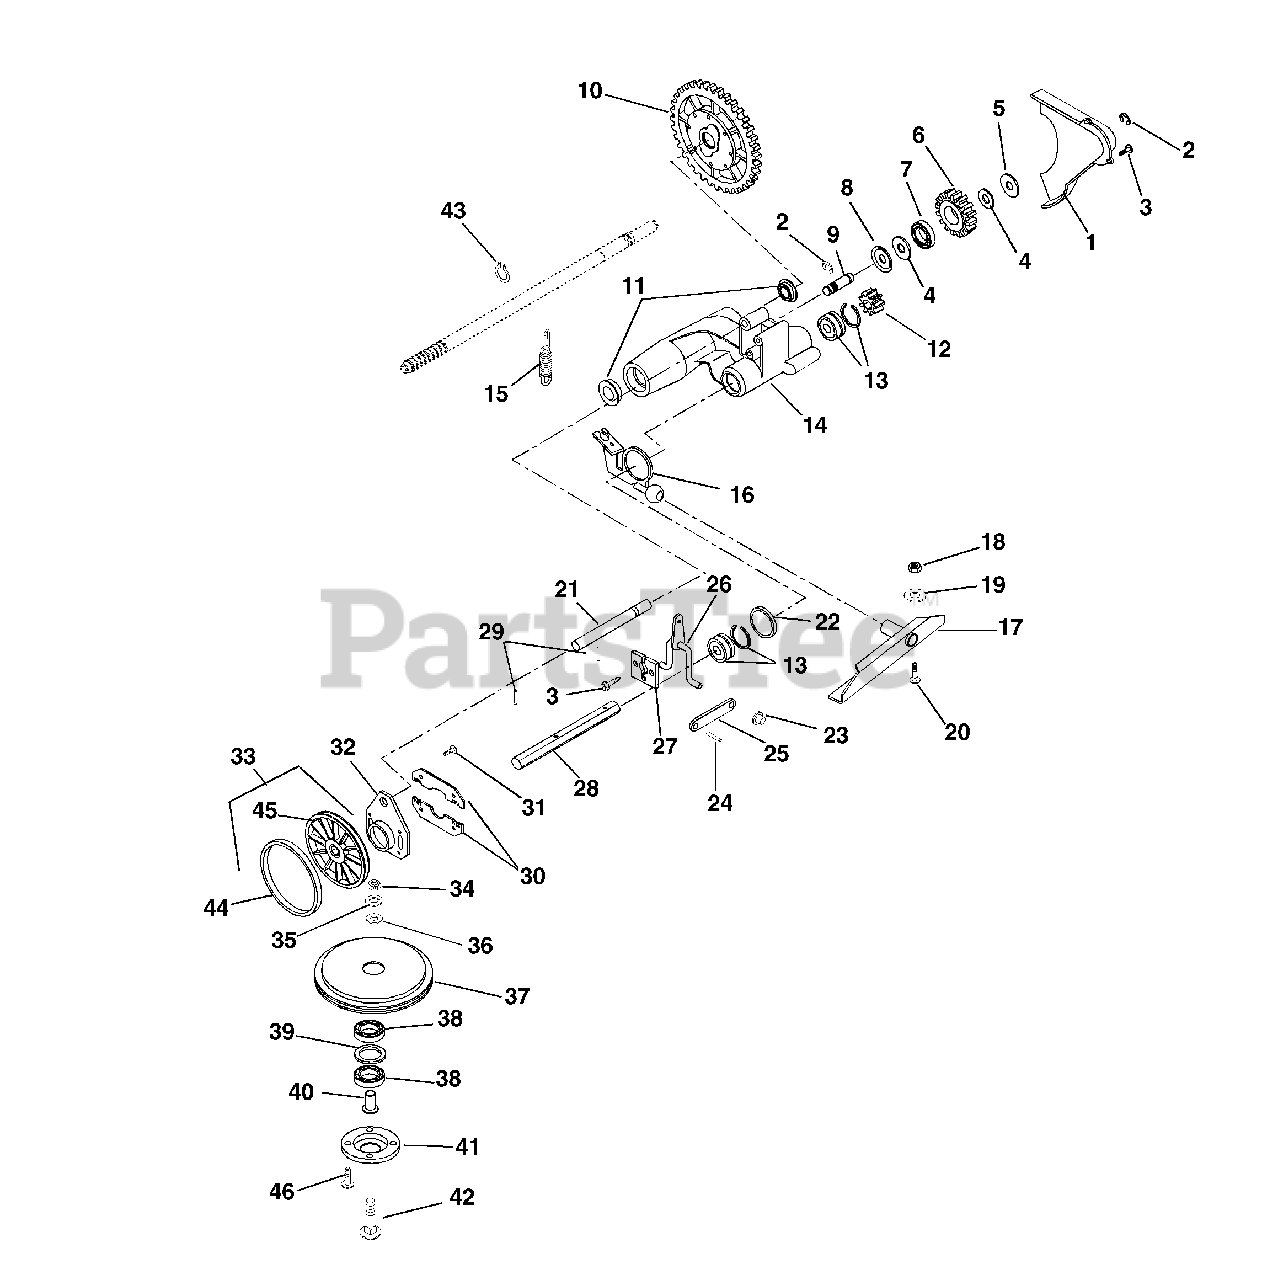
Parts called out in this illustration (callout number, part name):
1	COVER, GEAR
2	RG-RTNG-EXT .438X.035
3	@SCR-TAP 12-24X.50 HWH TR YWZC
4	WSHR-FL-STL .52X.827X.062 YWZC
5	WSHR-FL-STL.531X1.00X.063 YWZC
6	IDLER GEAR
7	BRG-BALL .500X1.38X.437
8	RETAINER
9	IDLER SHAFT
10	DIFFERENTIAL ASSEMBLY
11	BRG-BALL .625X1.383X.50
13	BRG-BALL .562X1.375X.437
14	DRIVE MOUNT
15	SG-TENS .051X.60X2.25 WLD 7.0
16	DRIVE ACTUATOR WELDMENT
17	PIVOT, CHANNEL WELDMENT
18	@NUT-LK-CTR .31-18 YWZC
19	@WSHR-FL-STL.344X.688X.065YWZC
20	@BLT-RHDSSQNK .31-18X.62 G5YZ
21	ROD - GUIDE
22	WSHR-FL-STL 1.390X2.00X.020 PL
23	PUSH NUT, .25
24	PIN-ROLL .125X.50
25	SHIFT LINK
26	SHIFT ARM WELDMENT
27	RETAINER PLATE
28	HEX SHAFT
29	PIN-ROLL .188X.88
30	THRUST PLATE
31	@SCR-TAP 10-24X.375 HWH YZ TR
32	GUIDE PLATE
33	FRICTION WHEEL ASSEMBLY
34	@NUT-HEX .31-18 YWZC
35	WSHR-LK .312X.097 HVY YWZC
36	WSHR-FL-STL .328X.875X.062YWZC
37	FRICTION SHEAVE
38	BRG-BALL .625X1.375X.43
39	WSHR-FL-STL 1.062X1.344X.032PL
40	SPINDLE - BEARING
41	RETAINER - BEARING
42	@BLT-RDHDSQNK .31-18X1.75 G5YZ
43	RG-RTNG-EXT .579X.035
44	RING, FRICTION
45	FRICTION WHEEL HUB
46	@SCR-TAP 12-24X.50 HWH TR YWZC
